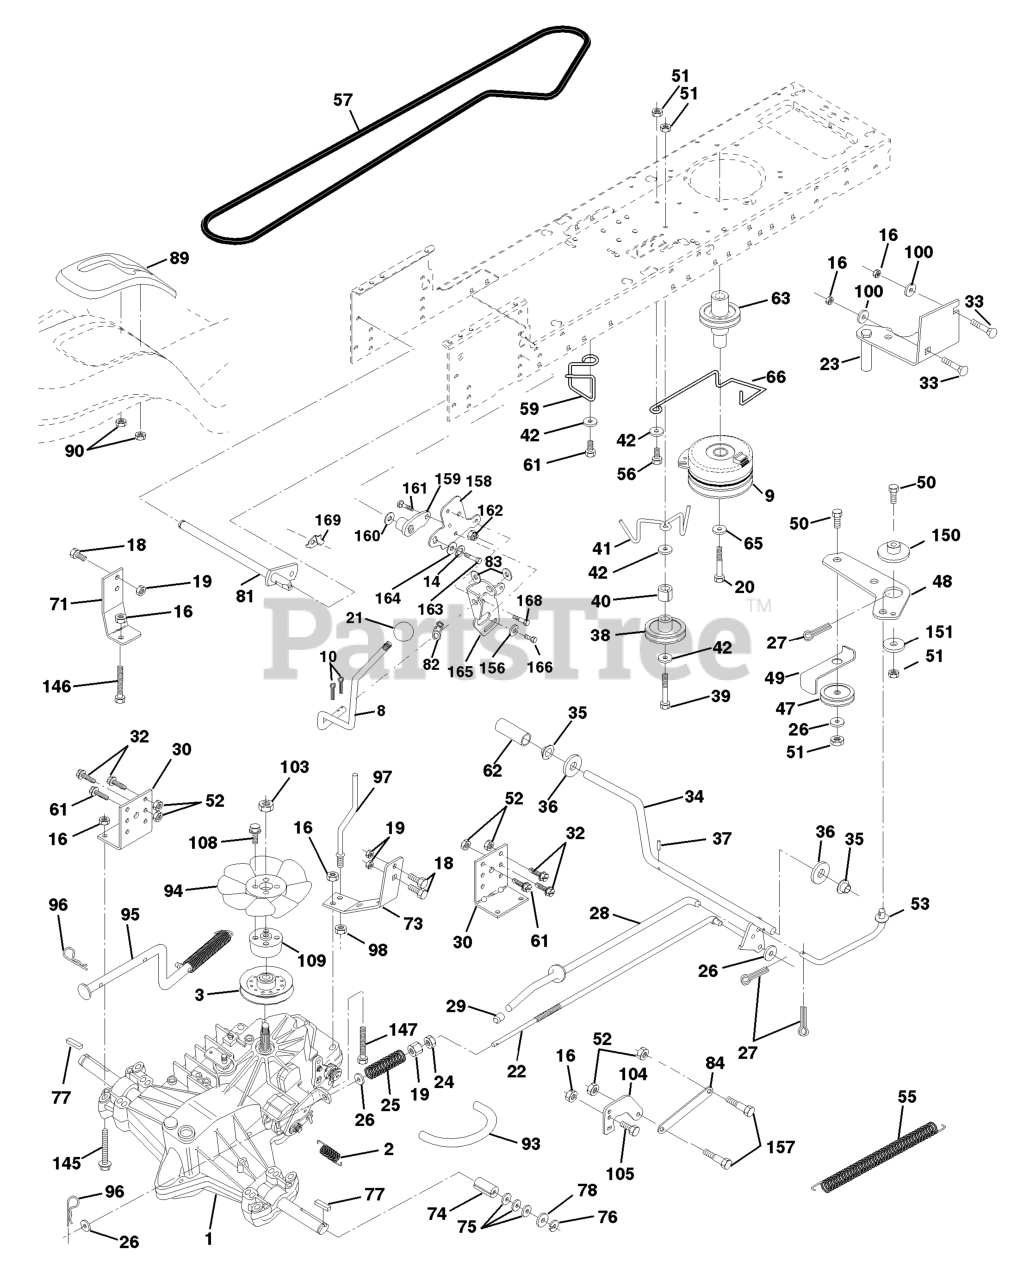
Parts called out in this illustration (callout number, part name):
1	TRANSAXLE.HYDRO.319-0500.LR
2	SPRING BRAKE
3	PULLEY.4.20.HYDRO
8	ROD SHIFT FENDER ADJUST STLT
9	CLUTCH.ELECT.EVX.
10	PIN COTTER
14	LOCKWASHER
16	NUT.71038.31-18.HEX.NYLOCK
18	BOLT
19	NUT
20	BOLT HEX
21	KNOB.DUCKHEAD.1/2
22	ROD BRAKE HYDRO
23	BRACKET, ASM CLUTCH MTG
24	NUT
25	SPRING ROD LT
26	WASHER
27	COTTER PIN
28	ROD BRAKE PARK LT
29	PLUNGER CAP
30	BRACKET TRANSAXLE
32	BOLT
33	RP BOLT 5/16-18 X3/4 ZN/YEL GR
34	SHAFT, FOOT PEDAL
35	BEARING.NYLON
36	WASHER LT
37	DRIVE PIN
38	FLAT IDLER PULLEY
41	KEEPER.BELT.IDLER.FLAT
42	WASHER
47	IDLER PULLEY
48	BELLCRANK, CLUTCH
49	RETAIN BELT
50	BOLT
52	LOCKNUT
53	LINK, CLUTCH LT
55	SPRING, RETURN LT
59	KEEPER CENTER SPAN
61	SCREW
62	PEDAL COVER T
63	PULLEY, CLUTCH ELECT EVX
65	LOCKWASHER
66	KEEPER BELT ENGINE
71	STRAP TORQUE LH HYDRO
73	STRAP TORQUE RH HYDRO
74	SPACER SPLIT
77	SQUARE KEY
81	Shaft Asm Cross Tapered
82	SHIFT SPRING
83	WASHER
84	Link Transaxle
89	SHIFT CONSOLE
90	NUT.PUSH.3/16
93	LINE FUEL HYD 4"
94	FAN 7" HYDRO
95	CONTROL ARM, BYPASS HYDRO
96	RETAINER M
97	KEEPER BELT RH
100	WASHER M
103	NUT.HEX.1/2-20
104	ARM, CONTROL HYDRO
106	BOLT.5/16-18X1-1/4 FULL.THREAD
109	ADAPTOR FAN HYDRO
144	Washer 11/32 x 5/8 x 16 Ga.
145	BOLT
146	Bolt Fin Hex 5/16-18 x 2-1/4
147	Bolt Fin Hex 5/6-18 Unc x 1-1/2
150	BUSHING.BELLCRANK.GRD.DR
151	WASHER 12/32X2X10GA
156	WASHER.SRRTD.5/16
157	BOLT SHOULDER 5/16-18
158	BRACKET
159	HUB
160	Washer 29/32 x 1-1/4 x 16 Ga.
161	BOLT
162	NUT.CROWNLOCK.1/4
163	BOLT
164	Washer 5/8 x .281 x 10 Ga
165	RP BRACKET
168	BOLT.SHOULDER.5/16-18X
169	PLATE.FASTENING.CROSS.SHAFT
